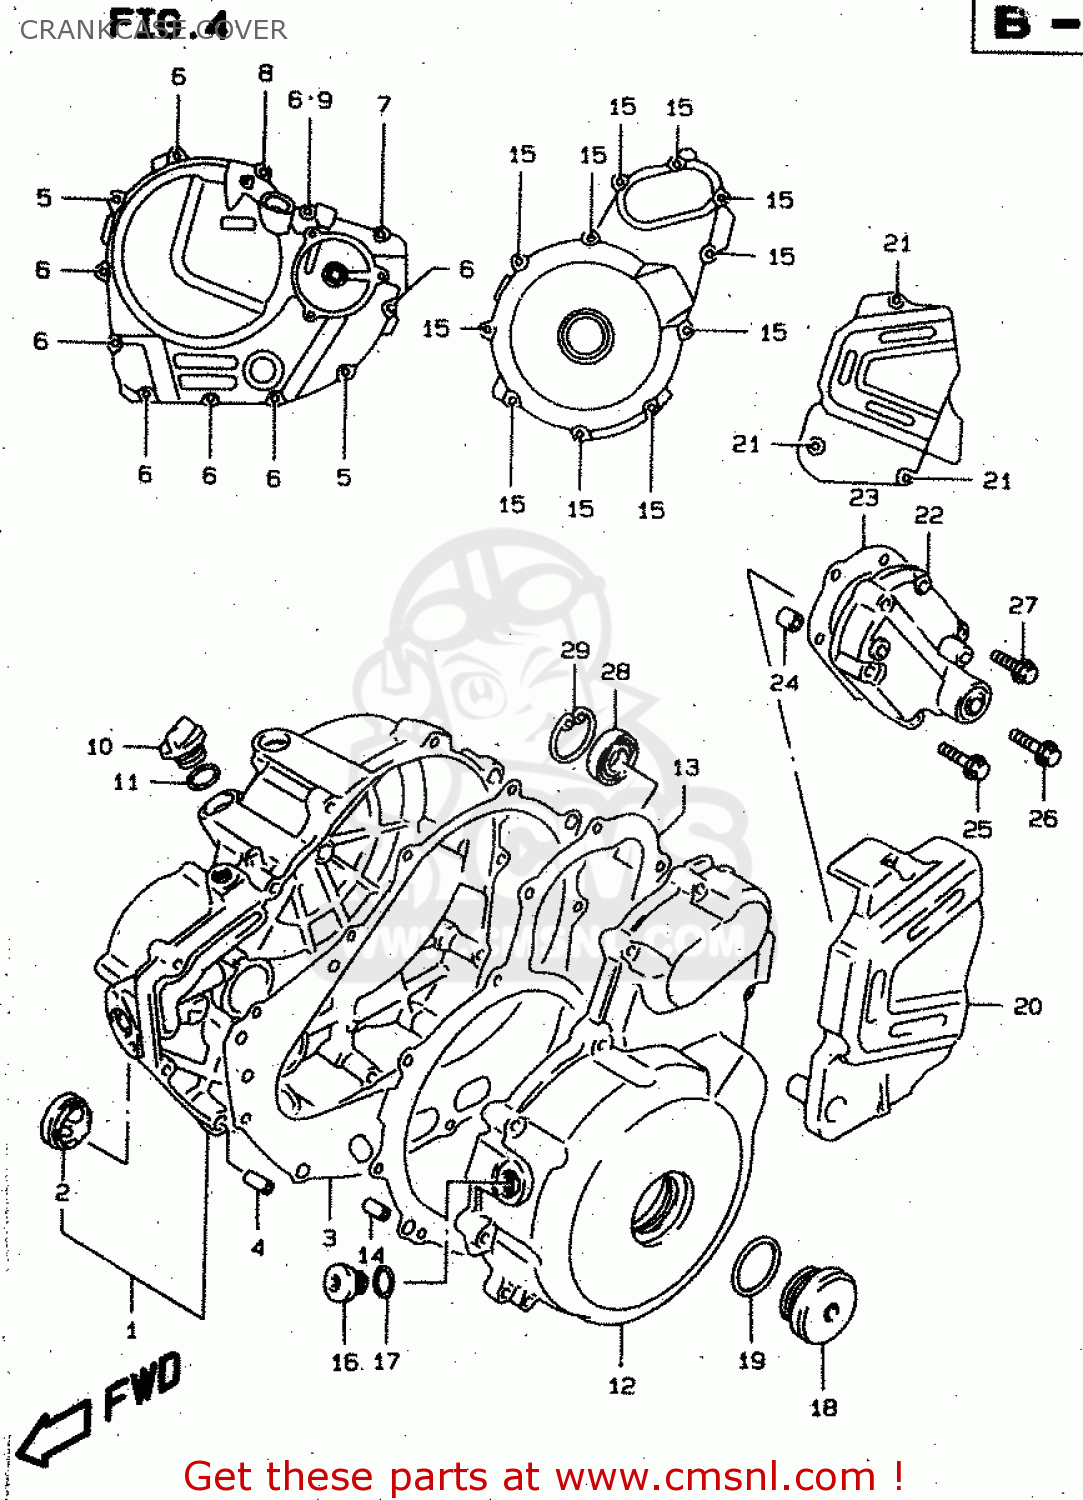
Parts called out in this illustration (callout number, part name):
1	COVER,CLUTCH
2	LENS,OIL LEVEL CHECK
3	GASKET,CLUTCH COVER
4	PIN
5	BOLT
6	BOLT
7	BOLT
8	BOLT
9	GASKET(5.8X11X1.2) (NAS)
10	PLUG
11	O RING(D:3.1,ID:16.8)
12	COVER,MAGNETO
13	GASKET,MAGNETO COVER
14	PIN
15	BOLT
16	PLUG,14X12
17	GASKET(13.8X18.8X4.8) (NAS)
18	PLUG(SILVER)
19	O RING(D:3.1,ID:32.7)
20	COVER,ENGINE SPROCKET
21	BOLT
22	COVER,GEAR SHIFT
23	GASKET,GEAR SHIFT COVER (NAS)
24	PIN
25	BOLT
26	BOLT,G/S SWITC
27	SCREW
28	BEARING(12X28X8)
29	CIRCLIP
